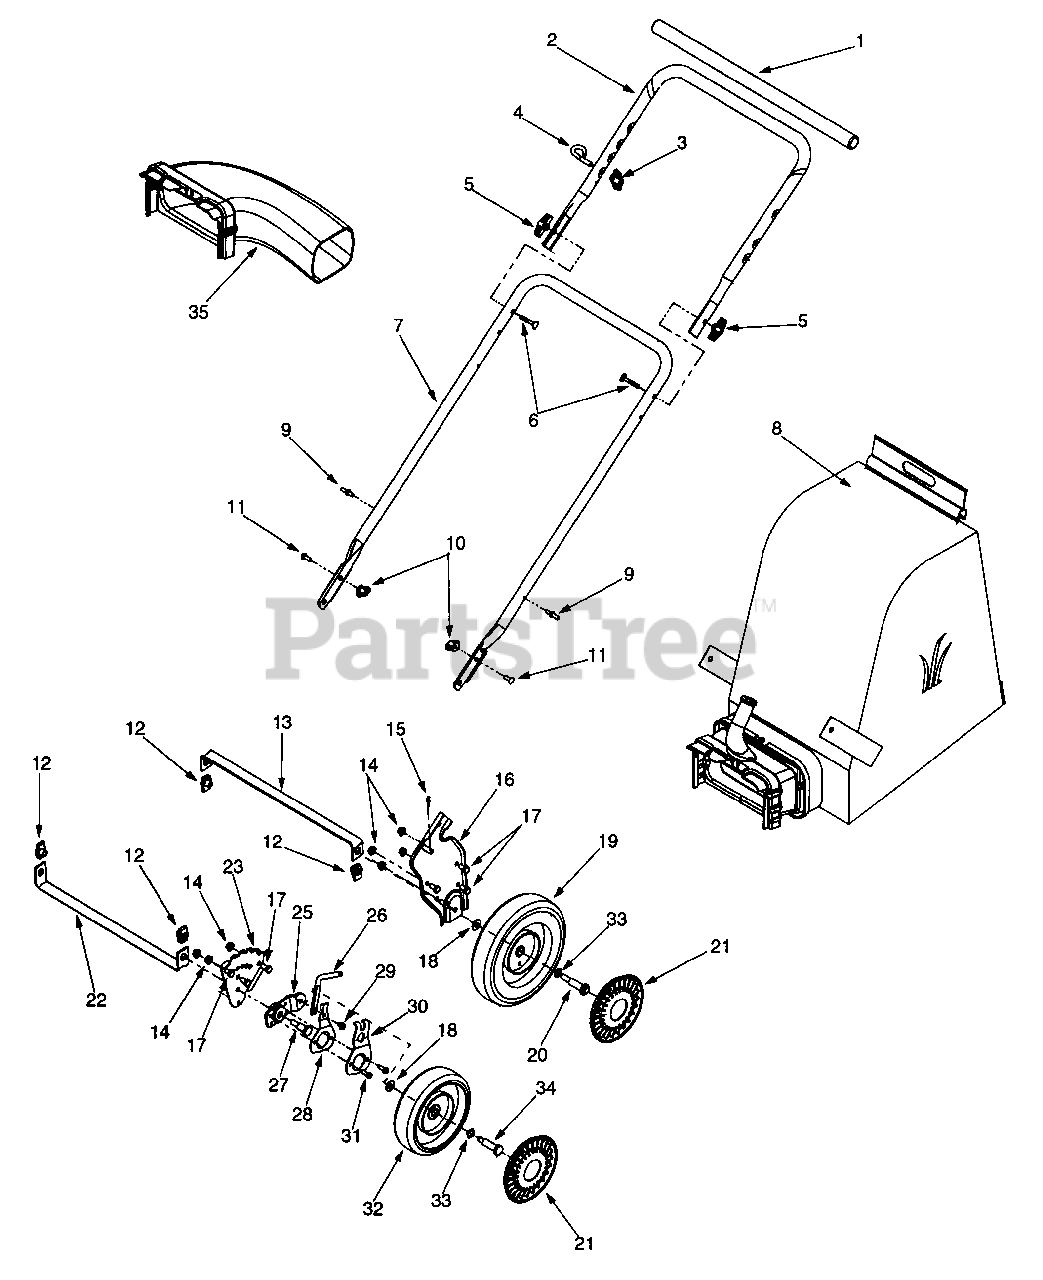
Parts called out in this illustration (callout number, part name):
1	Foam Grip
2	Upper Handle
4	Eye Bolt
5	Handle Knob 5/16-18
6	Carriage Bolt
8	Chute
9	Studs
10	Wing Nut 1/4-20
11	Carriage Screw 1/4-20 x .75
12	Lock U-Clip Nut 3/8-16
15	Cotter Pin
17	Hex Cap Screw 5/16-18 x .625
18	Bell Washer .401 ID x .870 OD
19	Wheel 9 x 2
20	Shoulder Screw 3/8-16
21	Hubcap
22	Front Wheel Support Brace
23	Hgt Bracket Adjuster LH
25	Pivot Arm
26	Handle Height Adjuster
27	Shoulder Screw 3/8-16
28	Height Adjuster Plate Spring
29	Hex Washer Screw 1/4-20 x .375
32	Wheel 8 x 2
33	Wave Washer .531 ID x .781 OD
34	Shoulder Screw
35	Blower Chute Assembly
